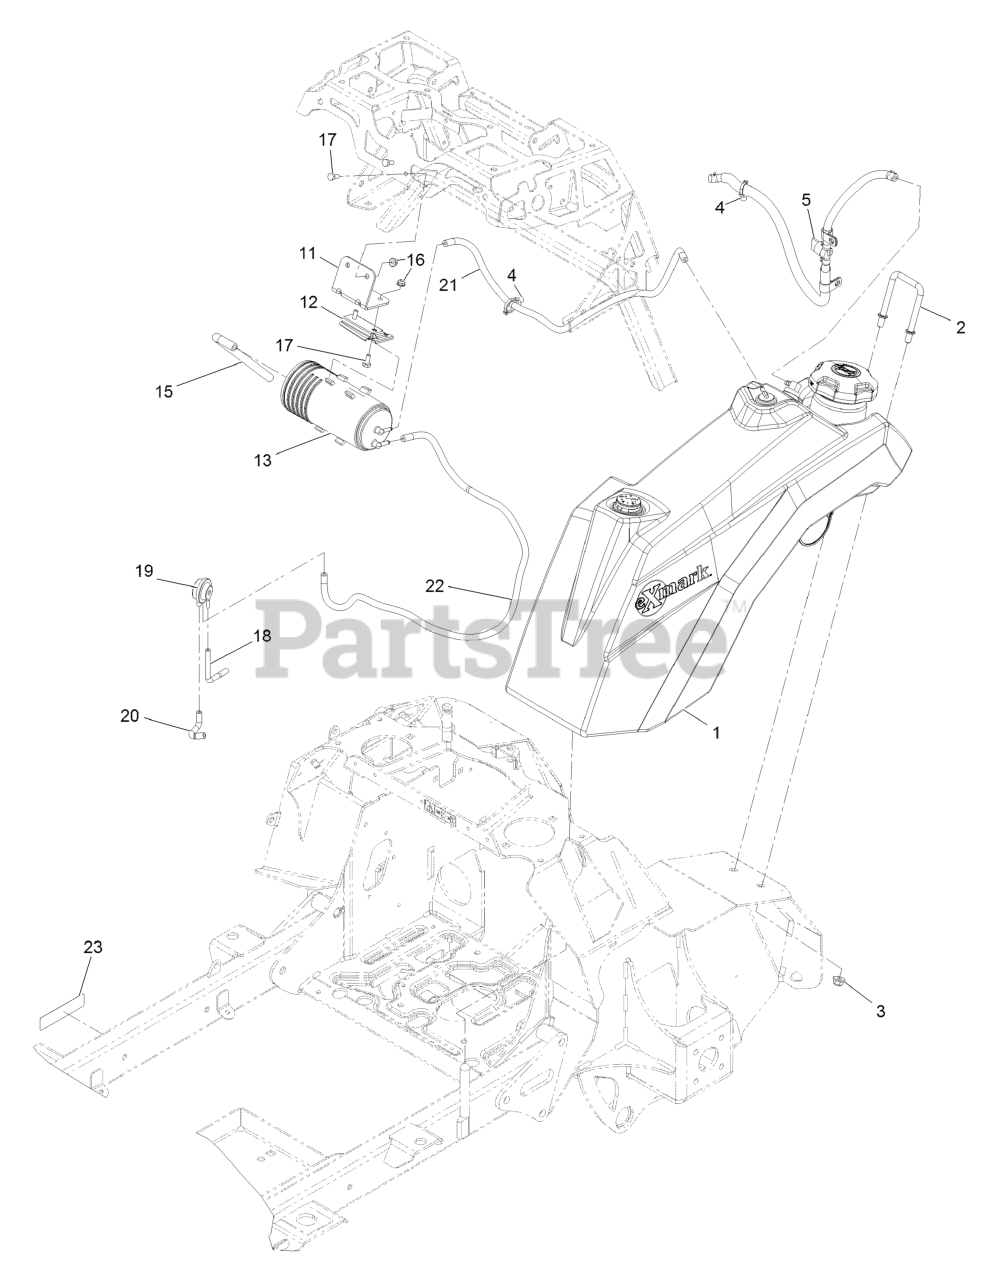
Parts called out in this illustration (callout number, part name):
1	ASSEMBLY, FUEL TANK
2	CLAMP, TANK
3	NUT-HF, NI
4	CLIP-TIE
5	ASM-FUEL LINE & VALVE
11	Bracket-Carbon Canister
12	BRACKET-CANISTER, CARBON
13	CANISTER-CARBON, 800CC
15	HOSE-VENT, CANISTER
17	SCREW-HH
18	HOSE-VENT, FORMED
19	VALVE-CONTROL, VACUUM
20	HOSE-VENT, FORMED
21	HOSE-FUEL
22	HOSE-FUEL
23	DECAL-ARRESTOR, SPARK
